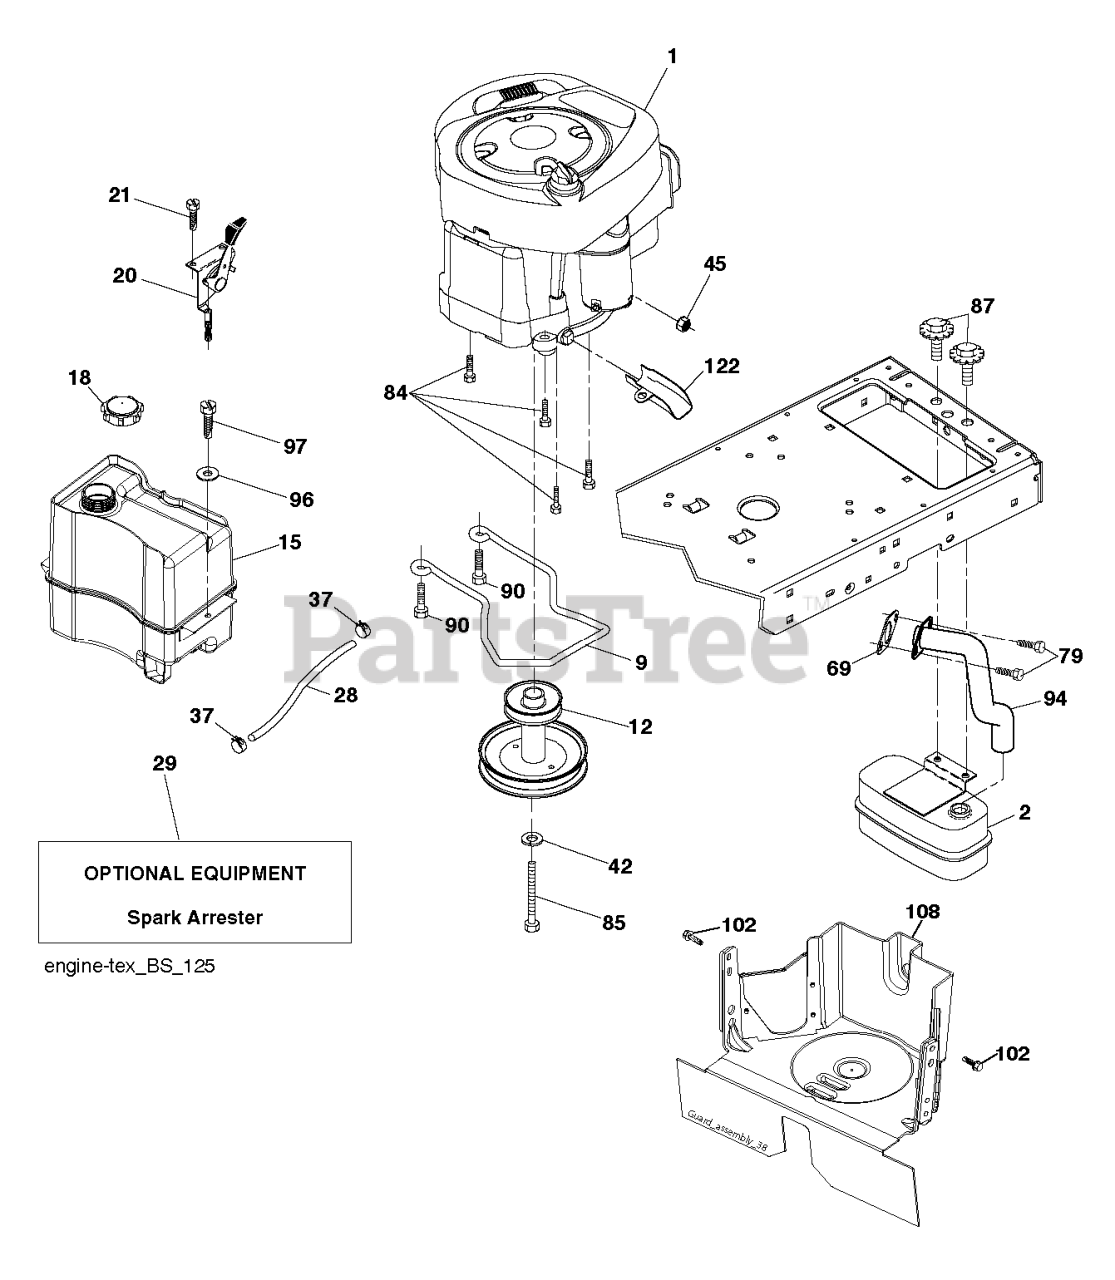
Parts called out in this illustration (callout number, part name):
2	MUFFLER.SINGLE.CYL.KOHL/B&S
9	KEEPER.BELT.ENG.4.25"2.BLT.431
12	ENGINE.PULLEY
15	FUEL.TANK.ASM.NON-EPA
18	CAP ASM.FUEL.2.25"FR.
20	THROTTLE.COBRA.21".RSTART.BLK
21	SCREW.#10 X 0.750.BOS
28	LINE.FUEL.20
29	KIT.SPARK ARRESTOR 794945 B&S
37	HOSE CLAMP
42	WASHER 7/16 LOCK
45	NUT
69	REPL BY 532 27 22-93
79	SCREW.SOCKET HD.5/16-1
84	SCREW.3/8-16
85	BOLT.HEX.7/16-20X4.GR5.1.5BLUE
87	BOLT.5/16-18UNCX3/4 W/SEMS.BLK
90	SCREW 3/8-16X1
94	EXHAUST.TUBE.B&S.28/31
97	SCREW HEXWSHR 1/4-20X3/4
102	SCREW 5/16-18X1
108	COVER ENGINE PULLEY COVER WITH
122	EXTENSION DRAIN OIL
